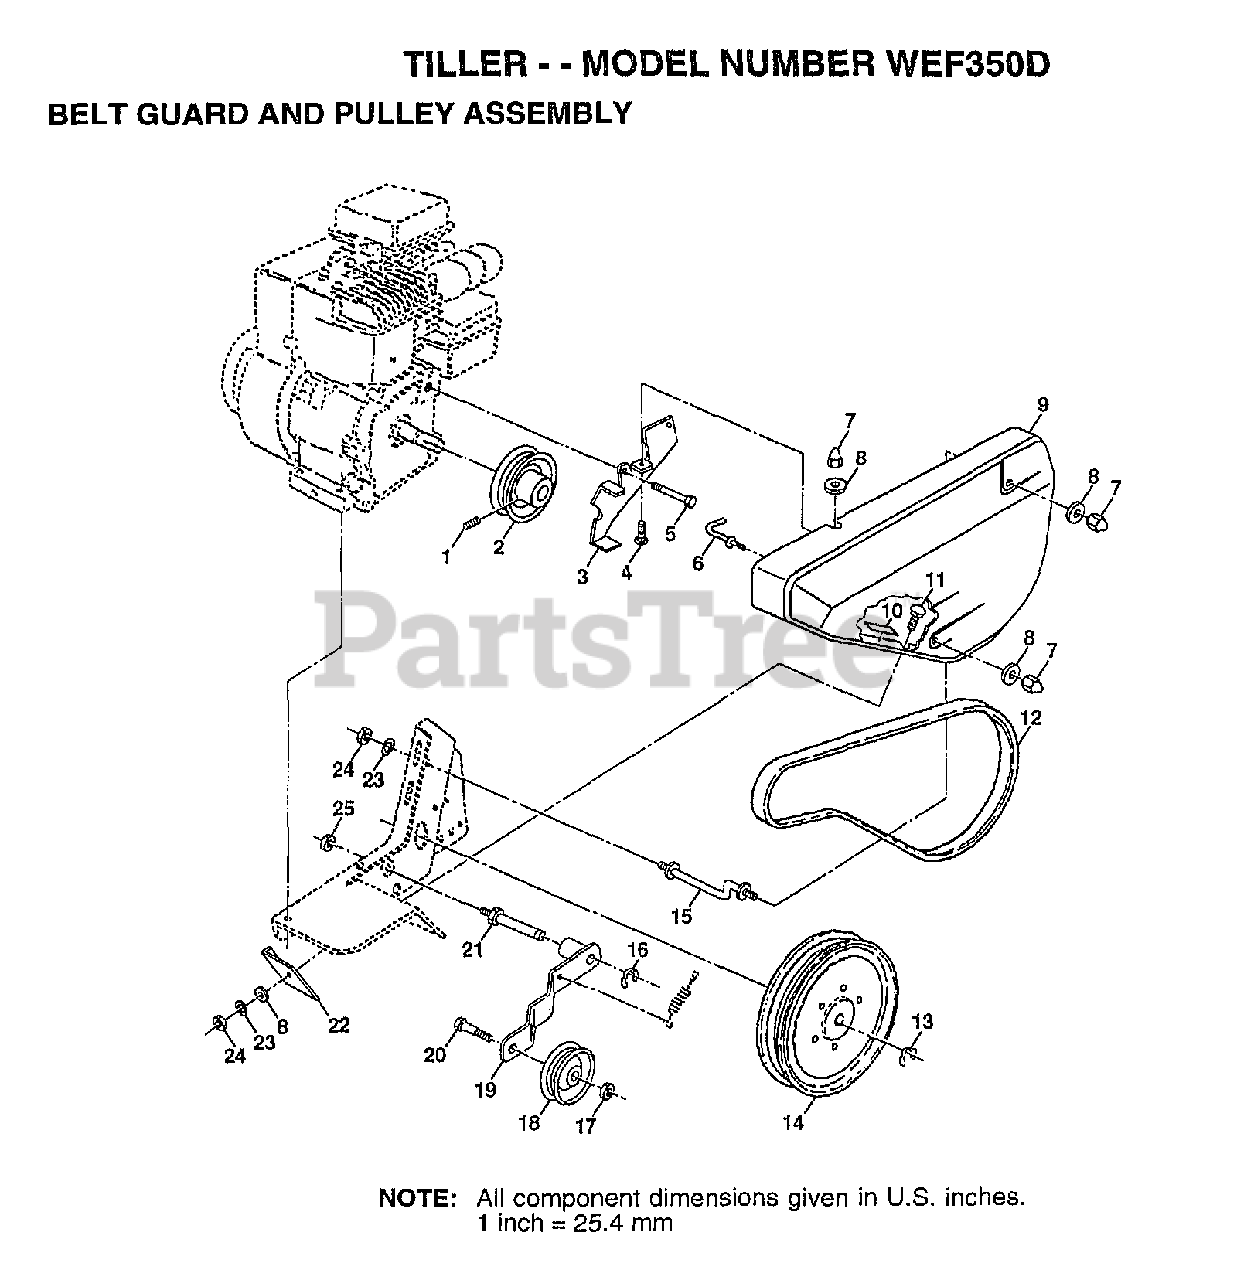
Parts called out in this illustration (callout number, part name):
1	SET SCREW
4	BOLT
5	BOLT.HEX.HEAD
7	NUT-CAP TI
8	WASHER
9	GUARD.BELT.TILLER
10	PAD IDLER TI
11	BOLT T
14	PULLEY.TRANSMISSN
16	KLIP RING TI
17	NUT
18	"PULLEY,IDLER"
19	"ARM, IDLER"
21	SHAFT IDLER TI
22	SHIELD-DIRT TI
23	LOCKWASHER
25	JAM NUT TI
